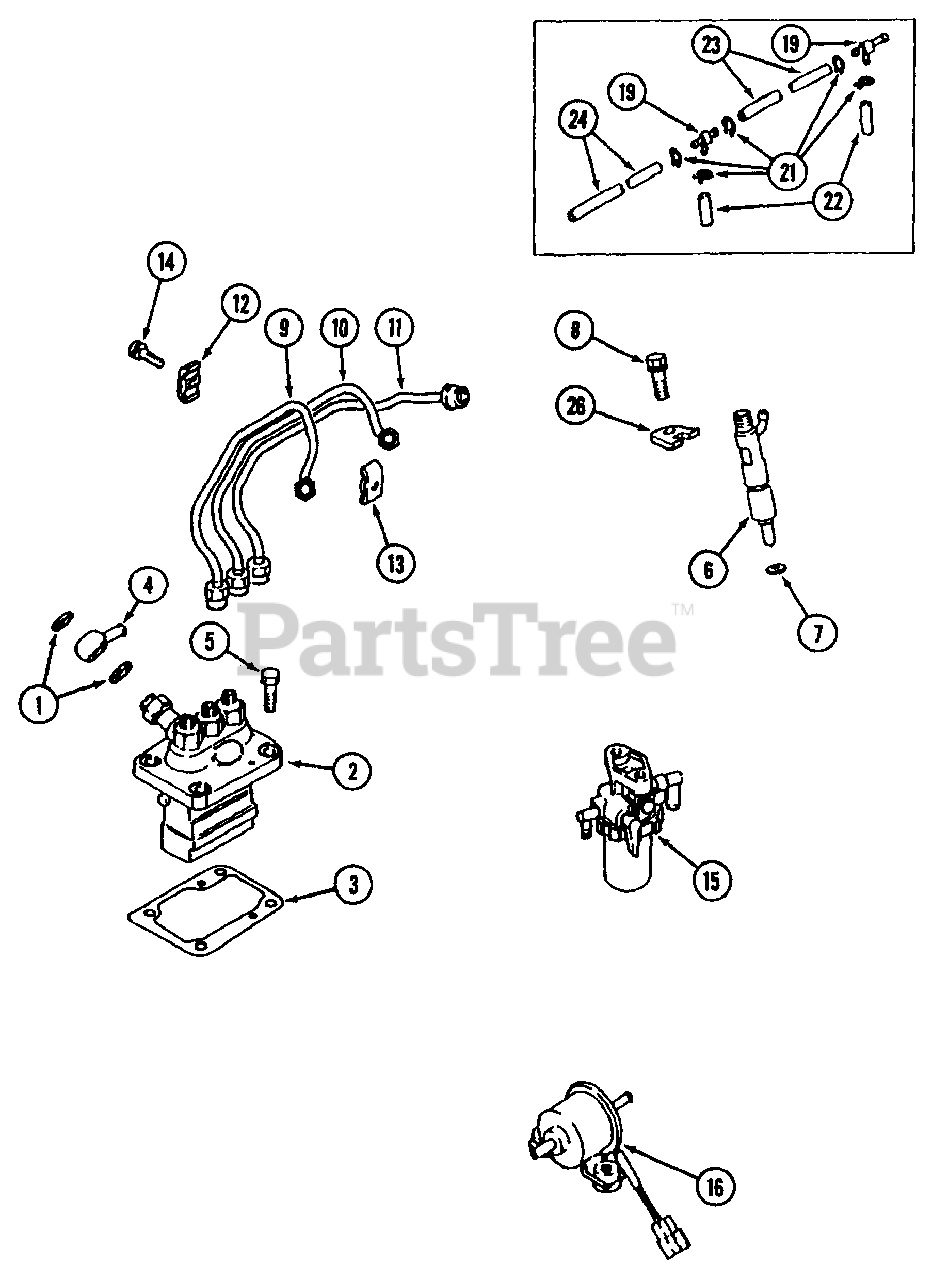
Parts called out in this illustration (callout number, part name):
2	Pump Ass'y., Fuel Injection
3	Shim Set, Adjusting T=0.2
4	Collar, Union
5	Bolt
6	Nozzle & Holder Ass'y.
7	Gasket, Nozzle Holder
9	Pipe Ass'y., Fuel Injection No.1
10	Pipe Ass'y., Fuel Injection No.2
11	Pipe Ass'y., Fuel Injection No.3
14	Bolt, W/Washer
15	Filter Ass'y., Fuel
16	Pump Ass'y., Electric,Fuel
21	Clamp, Hose
22	Pipe, Rubber
23	Pipe, Rubber
24	Pipe, Rubber
26	Support Nozzle
